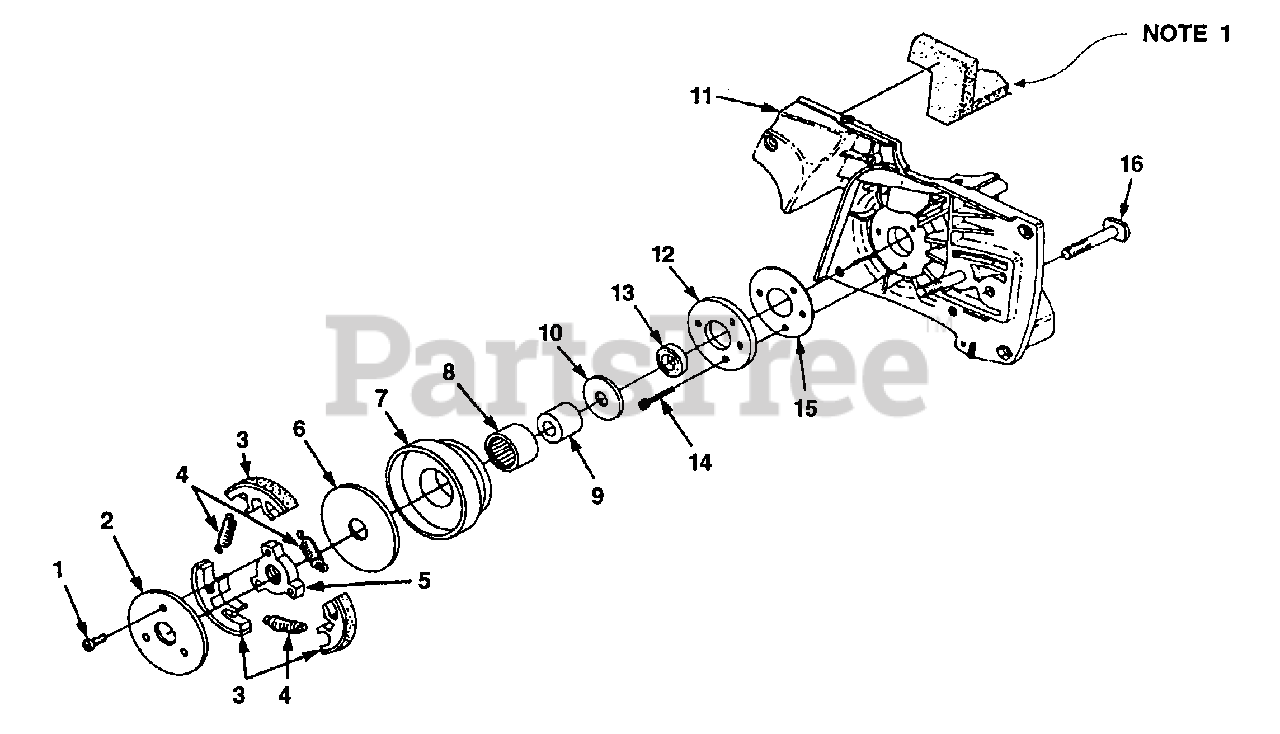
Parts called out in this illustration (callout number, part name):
1	SCREW - Hex Sems (8-32 X 3/4")
2	CLUTCH COVER
3	CLUTCH SHOE
4	CLUTCH SPRING
5	CLUTCH SPIDER
6	WASHER - Thrust
7	PULLEY & DRUM
8	NEEDLE BEARING
9	RACE - Inner
10	WASHER - Thrust
11	CRANKCASE ASSY (COMPLETE)
12	RETAINING - Bearing
14	SCREW - Socket Cap (10-24 X 5/8")
15	GASKET
16	WHEEL ARM BOLT (5-16-18 X 2.5")
